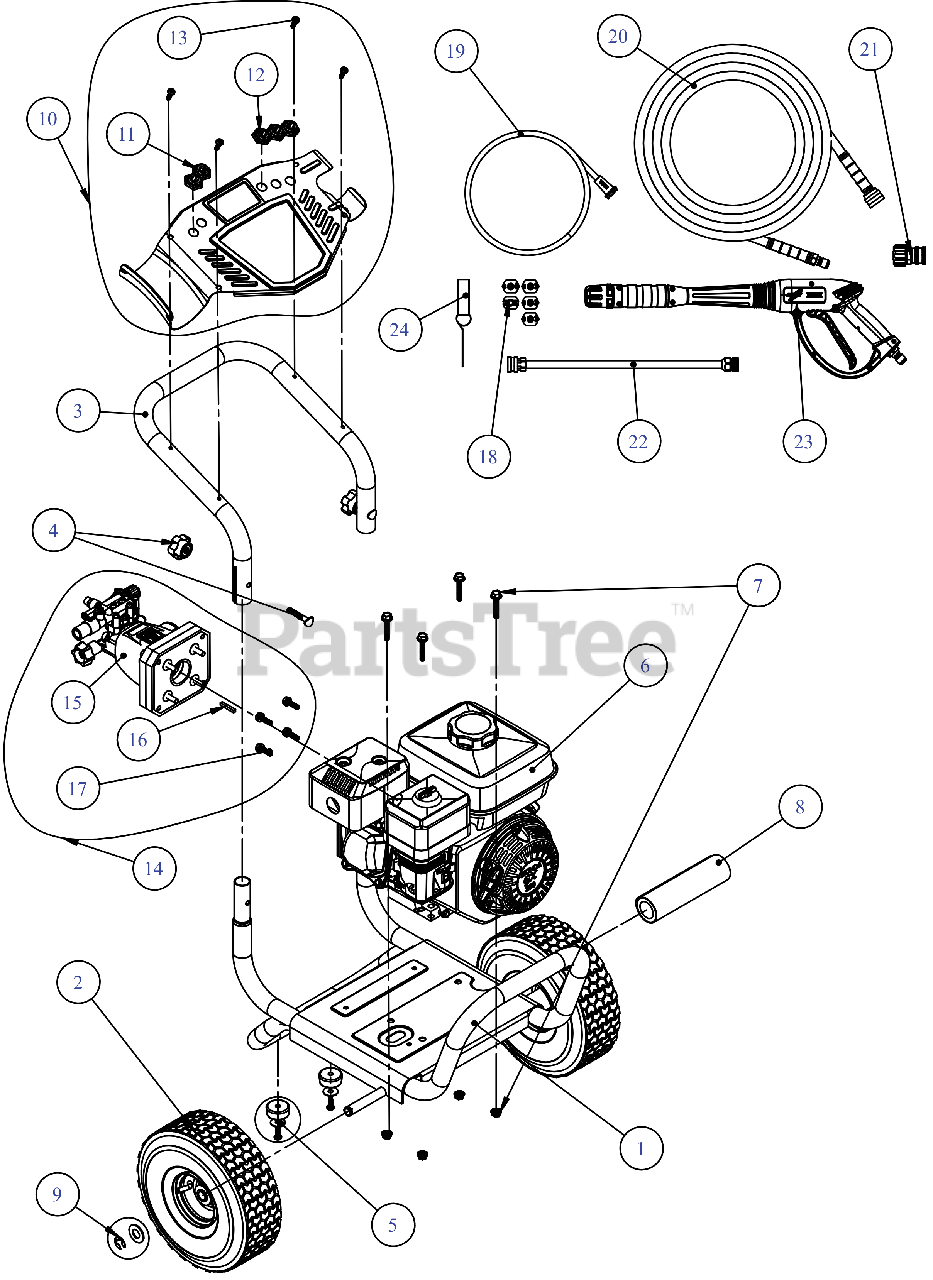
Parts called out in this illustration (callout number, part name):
1	BASE ASSEMBLY-FRAME
2	WHEEL ASSEMBLY
3	UPPER HANDLE
4	KNOB-HANDLE MTG
6	ENGINE SVC ASSY W/ LABELS,
7	MOUNTING KIT: ENGINE
8	GRIP-HANDLE
9	WHEEL MOUNTING KIT
10	DASHBOARD PANEL (W/LABEL CC 3600)
11	HOLDER-NOZZLE 2 PC
12	HOLDER-NOZZLE 3 PC
13	DASHBOARD MOUNTING KIT (4-SCREWS)
16	SHAFT KEY (3/16x3/16x1.25)
17	HARDWARE KIT: PUMP MOUNTING
18	5 PIECE NOZZLE SET
19	HOSE-SOAP W/FILTER
20	HOSE-SPRAY GUN 25'
21	ADAPTER-HOSE
22	WAND-SPRAY GUN 16"
23	SPRAY GUN REAR ENTRY
24	TOOL-NOZZLE CLEANING
